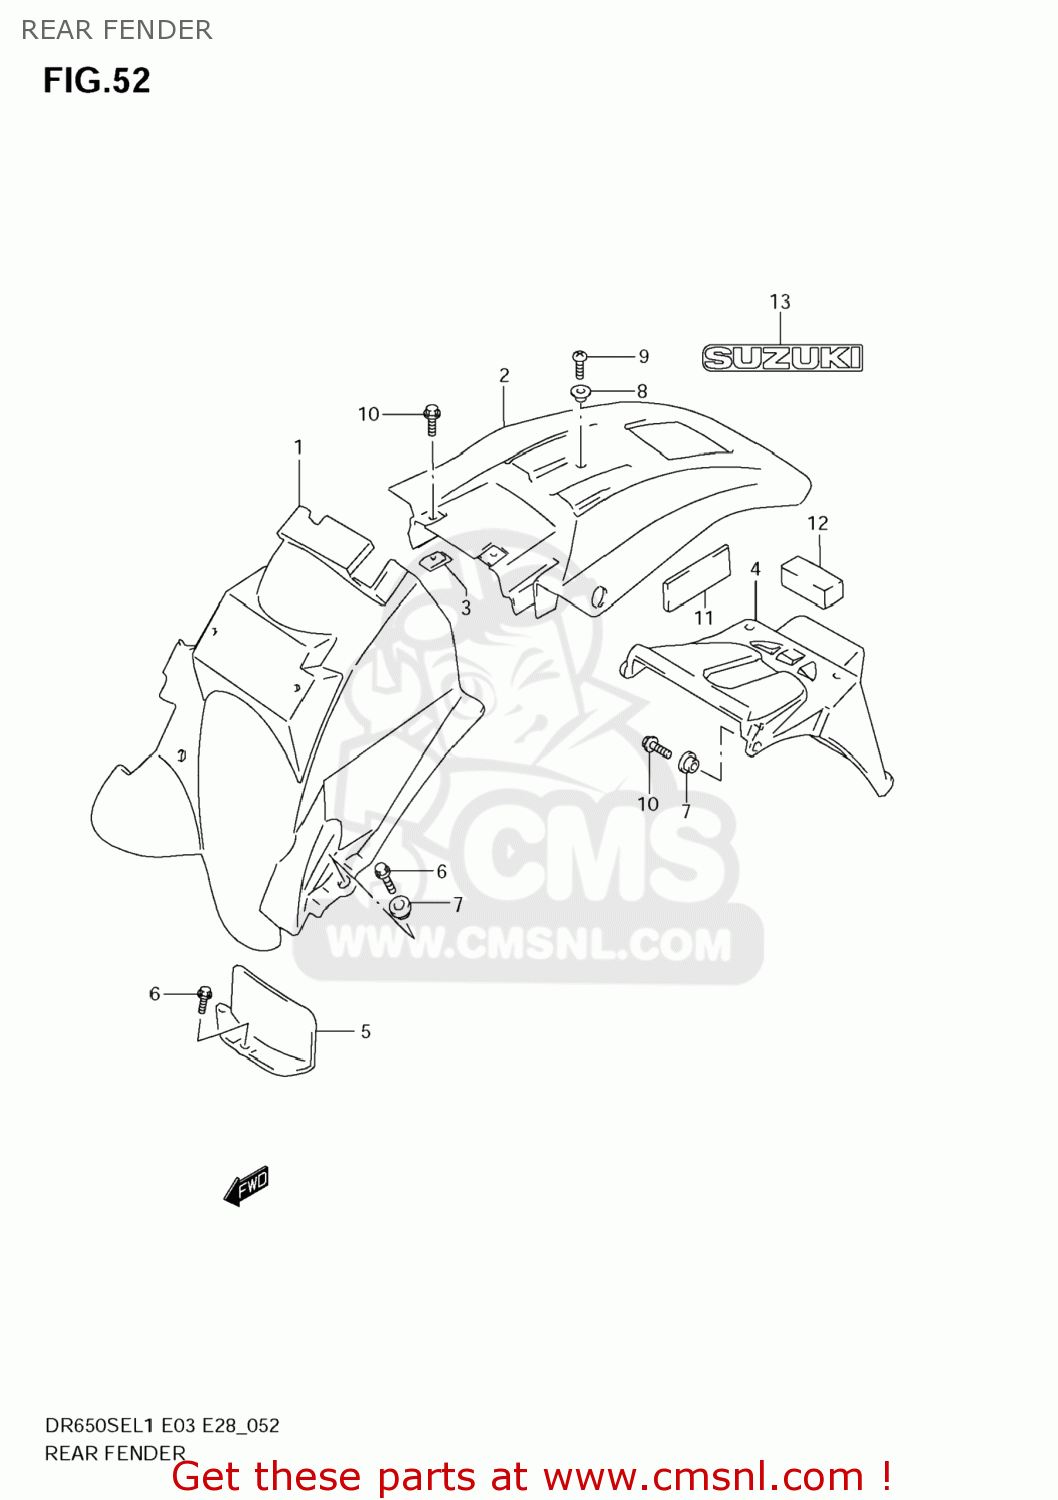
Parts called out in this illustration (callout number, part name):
1	BODY,RR FENDER FR
2	BODY,RR FENDER RR
3	PLATE,FRAME COVER
4	EXTENSION,RR FENDER
5	MUDGUARD,RR FENDER
6	BOLT(6X16)
7	WASHER
8	WASHER
9	SCREW(6X16)
10	BOLT
11	CUSHION,RR FENDER
12	CUSHION
13	EMBLEM
